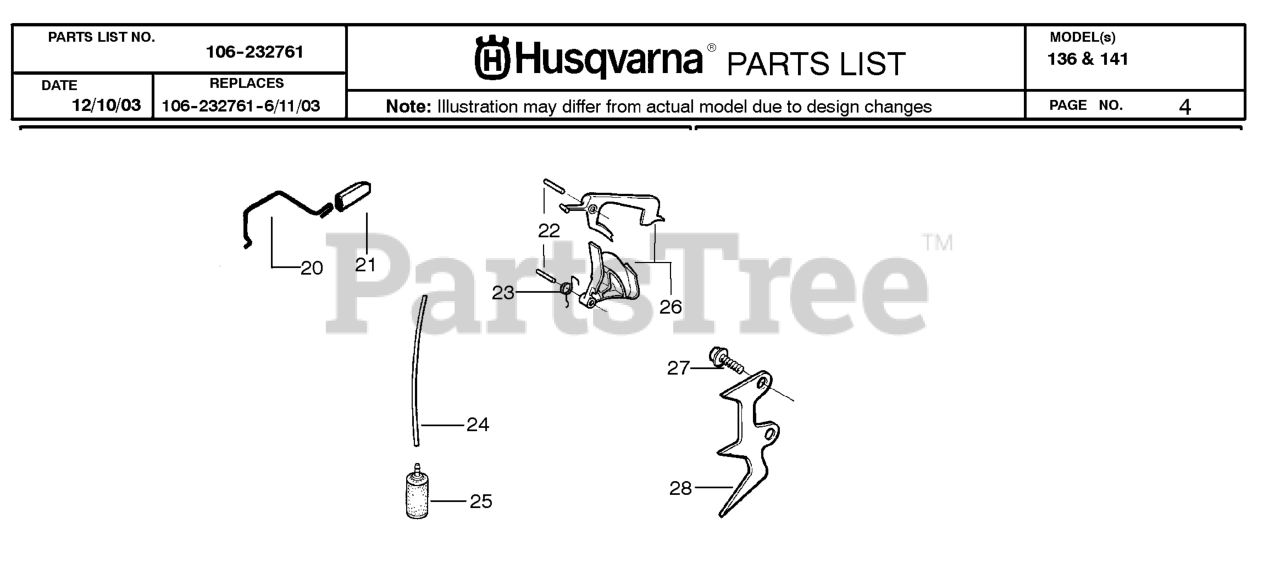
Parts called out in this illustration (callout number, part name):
20	THROTTLE SHAFT 36/41
21	THROTTLE ACTUATOR 36/41
22	PIN,TRIGGER 36/41
23	TRIGGER SPRING 36/41
24	HOSE. FUEL
25	FUEL PICK-UP
26	THROTTLE TRIGGER-KIT
27	SCREW-10-14 X 1/2 PLASTITE
28	SPIKE 36/41
